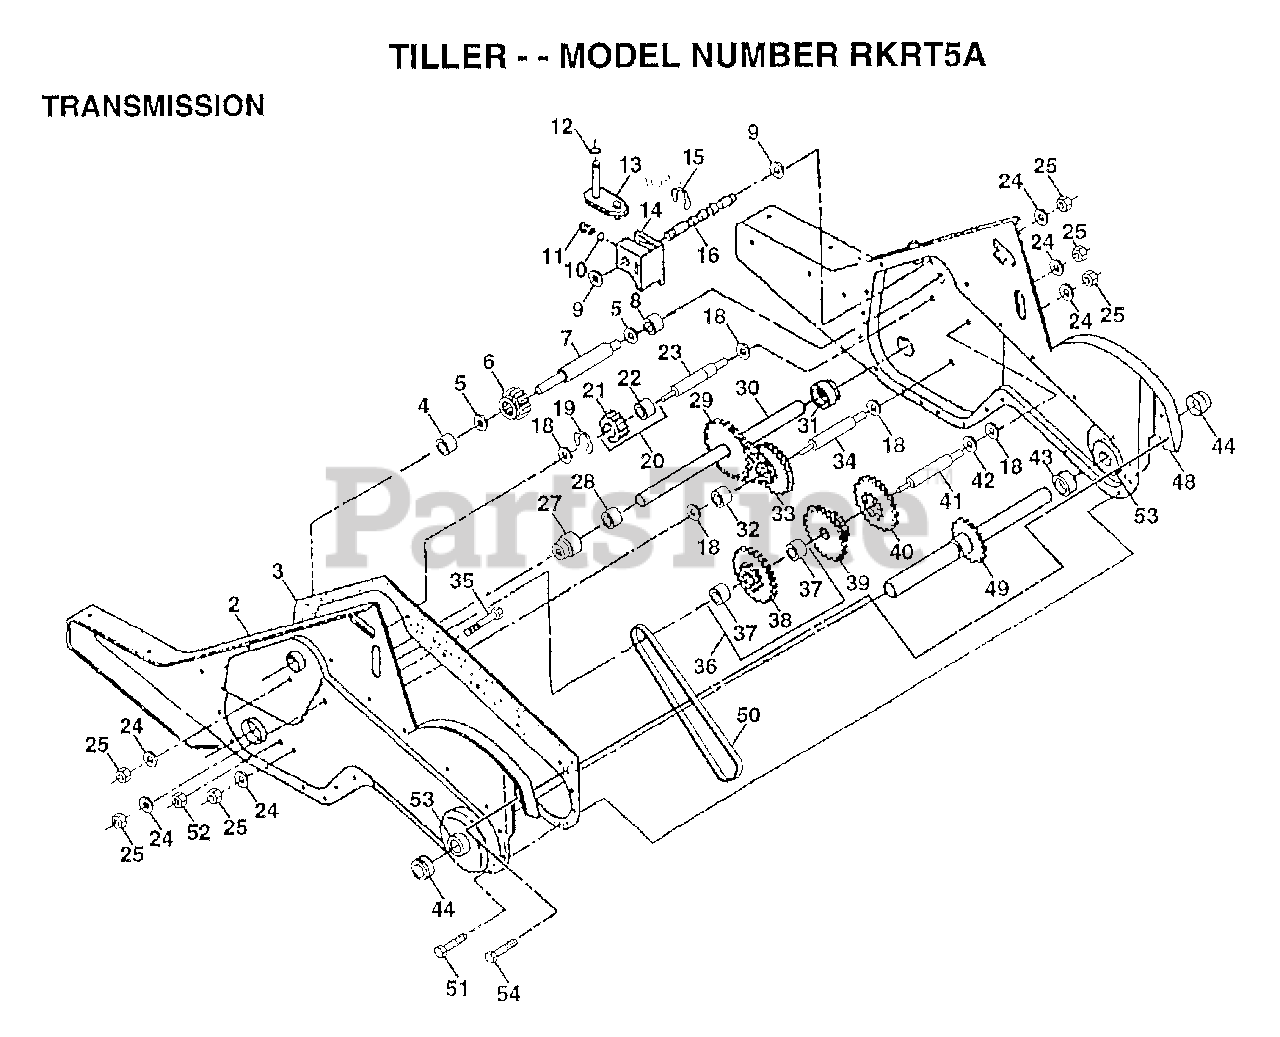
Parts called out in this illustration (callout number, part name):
2	GEARCASE LH W/BEARING
3	GASKET.GEARCASE
4	NEEDLE BRNG LT
5	"T, BEARING"
6	GEAR PINION INPUT
7	"SHAFT.INPUT.""D"""
8	"TI, BEARING"
9	WASHER SEAL
11	SPRING-SHIFT CRT
12	O-RING TI
13	BRACKET ASM SHIFT
14	SHIFT FORK TI
15	KLIP RING
16	SHAFT.SHIFTER
18	WASHER
19	KLIP RING
20	GEAR ASSY CRT
21	GEAR-REV IDLR CRT
22	NEEDLE BEARING TI
23	SHAFT CRT
24	LOCKWASHER
25	NUT.ASF.HEX.7/16
27	BEARING.SHAFT.LH.
28	BUSHING TI
29	CHAIN CRT
30	GROUND SHAFT ASSY
31	BEARING.SHAFT.RH.
32	SPACER TI
33	SPRCKT 8 GEAR CRT
34	SHFT 2ND RED. CRT
35	SCRW WHIZ LOK CRT
36	SPROCKET.ASM.W/BR
37	BEARING
39	GEAR TI
40	GEAR TI
41	REDUCTION SHFT TI
42	BRNG RACE
43	SPACER TI
44	SEAL ASM-OIL
48	GEARCASE RH W/BEARING
49	TINE SHAFT
50	CHAIN.50 LINK TI
51	SCREW
52	NUT.HEX.5/16-18
53	KIT.BEARING
54	SCREW 1/4-20X3/4
